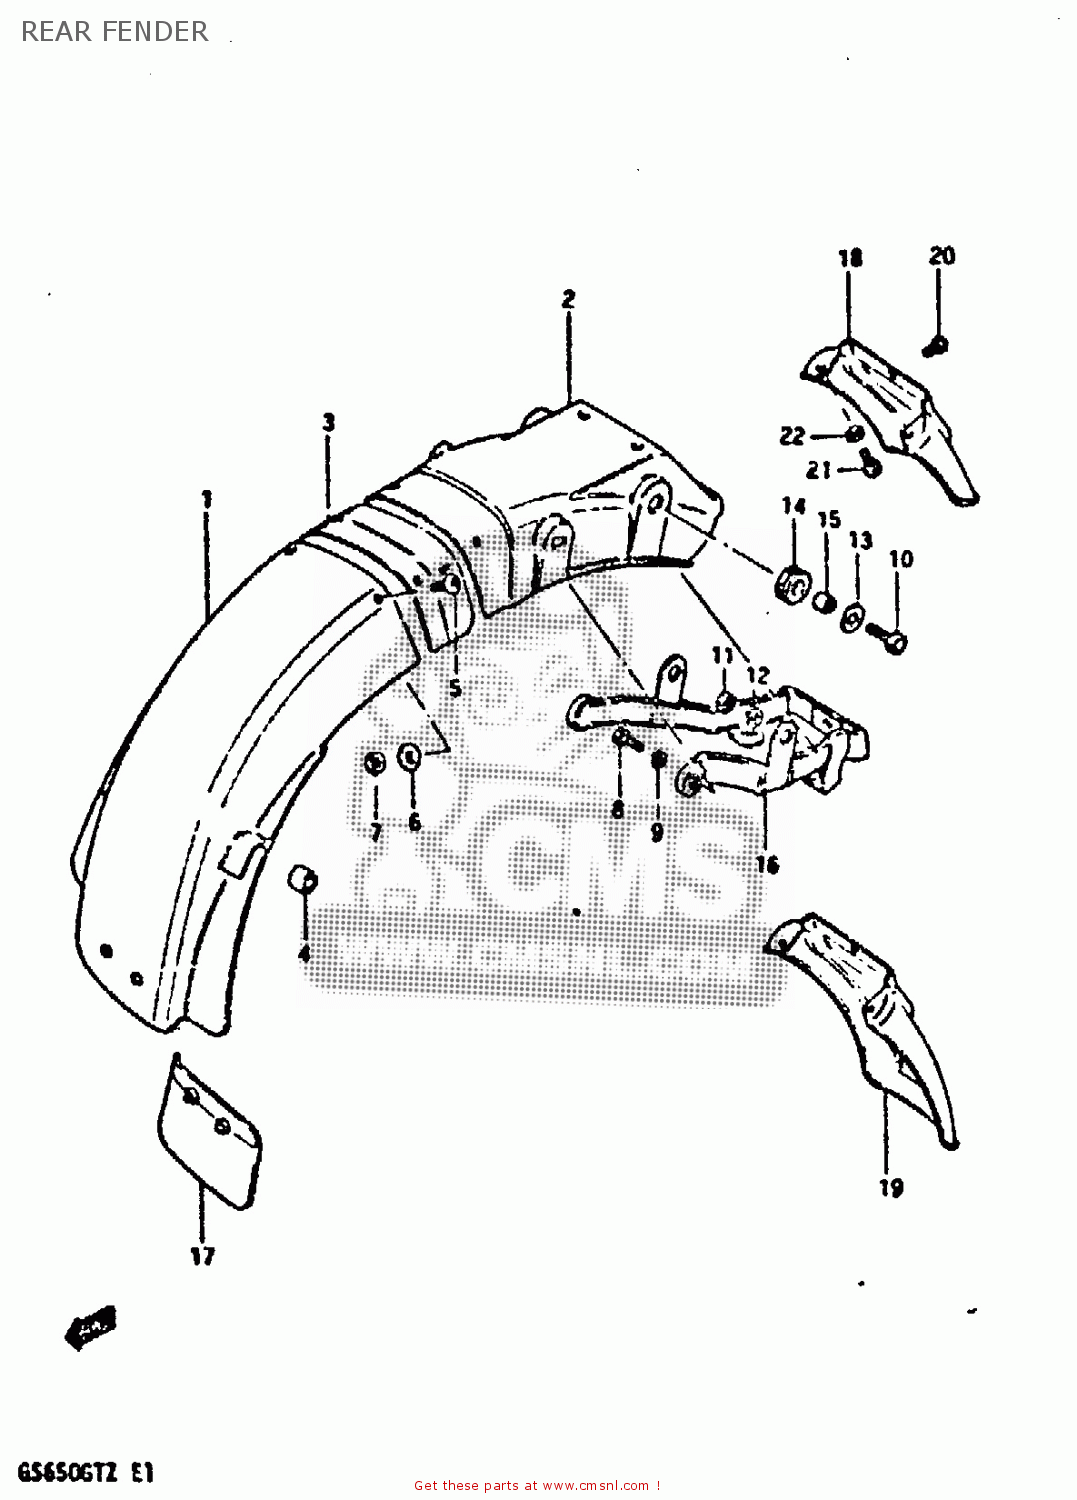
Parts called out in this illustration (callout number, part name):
1	BODY,REAR FENDER,REAR
2	BODY,REAR FENDER,REAR
3	JOINT,REAR FENDER
4	CUSHION
5	SCREW M5X12 DIN 7985/N
6	WASHER (5.5X16X1.2)
7	NUT
8	BOLT, UPPER
9	LOCK WASHER
10	BOLT (8X30)
11	NUT
12	LOCK WASHER
13	WASHER
14	CUSHION
15	SPACER (8.2X12X7.5)
16	REINFORCEMENT,REAR FENDER
17	GUIDE,RR FENDER MUD
18	EXTENSION,RR FENDER
20	SCREW
21	BOLT, UPPER
22	WASHER (6.5X20X1.2)
